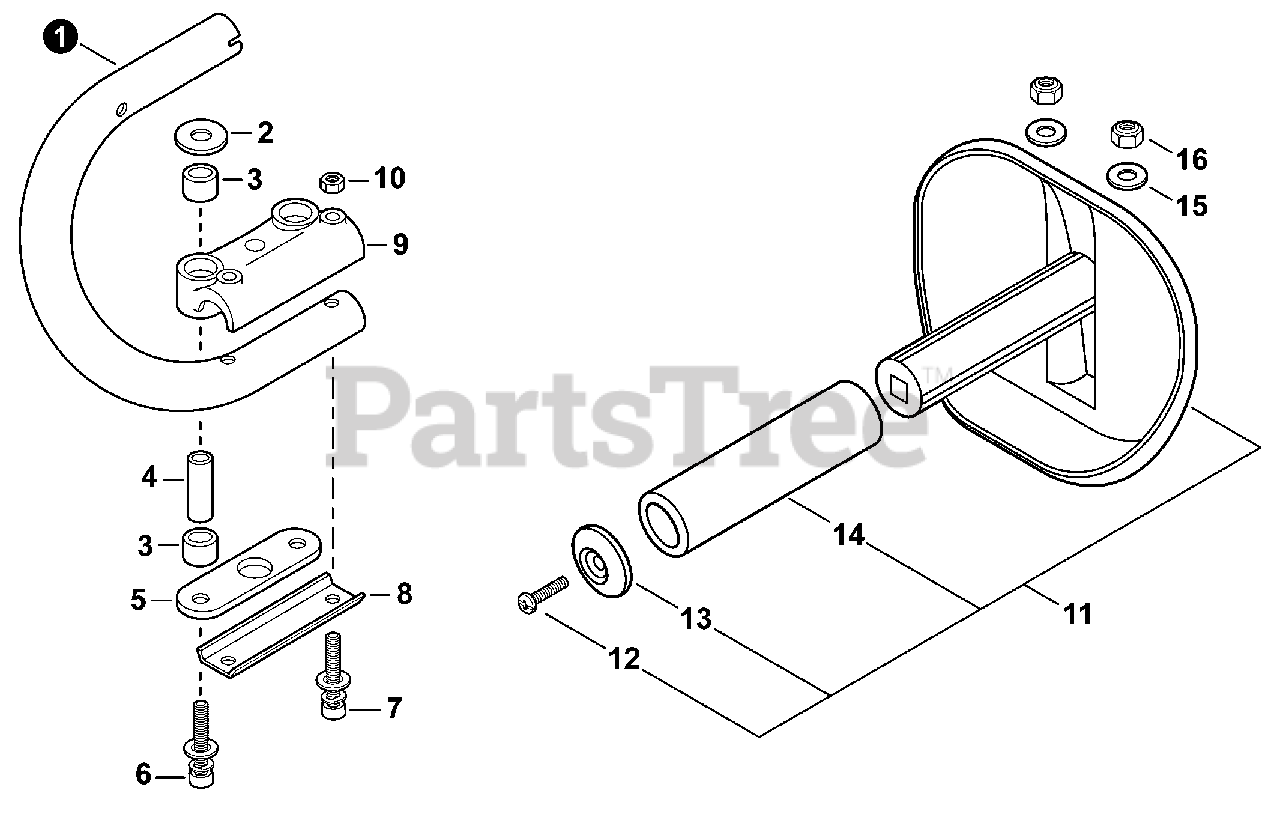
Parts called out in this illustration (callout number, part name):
1	HANDLE, REAR
2	WASHER 5.5×18×1
5	PLATE, EYE
6	BOLT 5×45
7	BOLT 5×35
9	BRACKET, HANDLE - UPPER
11	HANDLE ASSY, FRONT
12	SCREW 5×14
14	GRIP, HANDLE
15	WASHER 6.5×13×1
